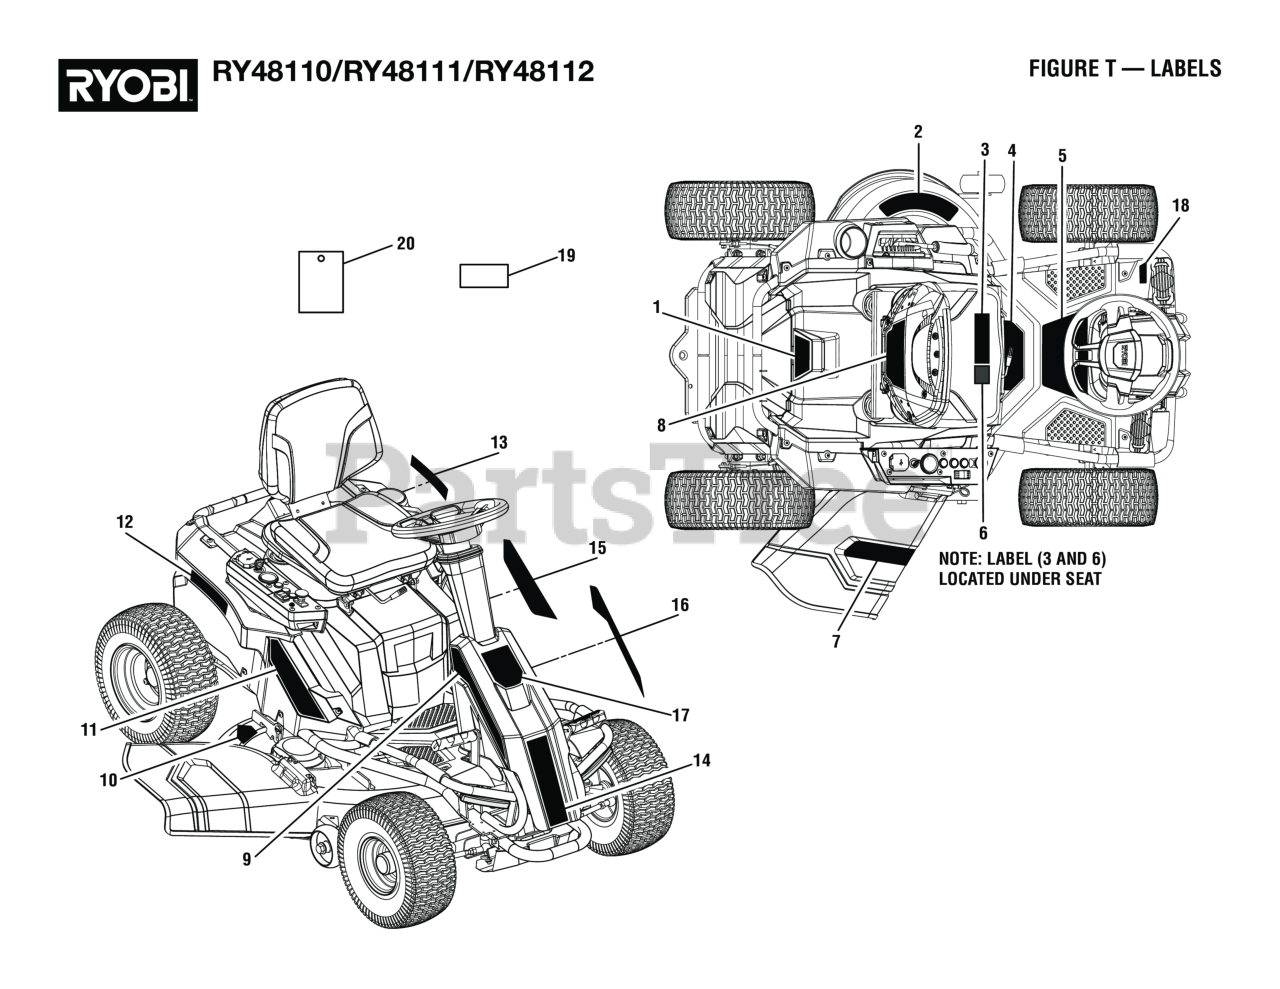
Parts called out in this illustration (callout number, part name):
1	Charging Port Label, English
1	Charging Port Label, English/French
1	Charging Port Label, Spanish
2	Deck Danger Label, English/French (RY48112)
3	Data Label (RY48112)
4	Starting Warning Label, English/French (RY48112)
5	Danger Label, English
5	Danger Label, English/French
5	Danger Label, Spanish
6	RPL Label, English
6	RPL Label, English/French
6	RPL Label, Spanish
7	Discharge Danger Label, English/French (RY48112)
8	Seat Back Panel
9	Right Stripes Label
10	No Hands CPSC Danger Label, English
10	No Hands CPSC Danger Label, English/French
10	No Hands CPSC Danger Label, Spanish
11	RM480e Label, Right
12	Ryobi Logo Label, Right
13	Ryobi Logo Label, Left
14	Front Column Logo Label
15	RM480e Label, Left
16	Left Stripes Label
17	Steering Column Logo Label
18	Brake Pedal Label, English/French (RY48112)
19	Watch For Kids, Keychain Label
20	Prop 65 Hangtag
